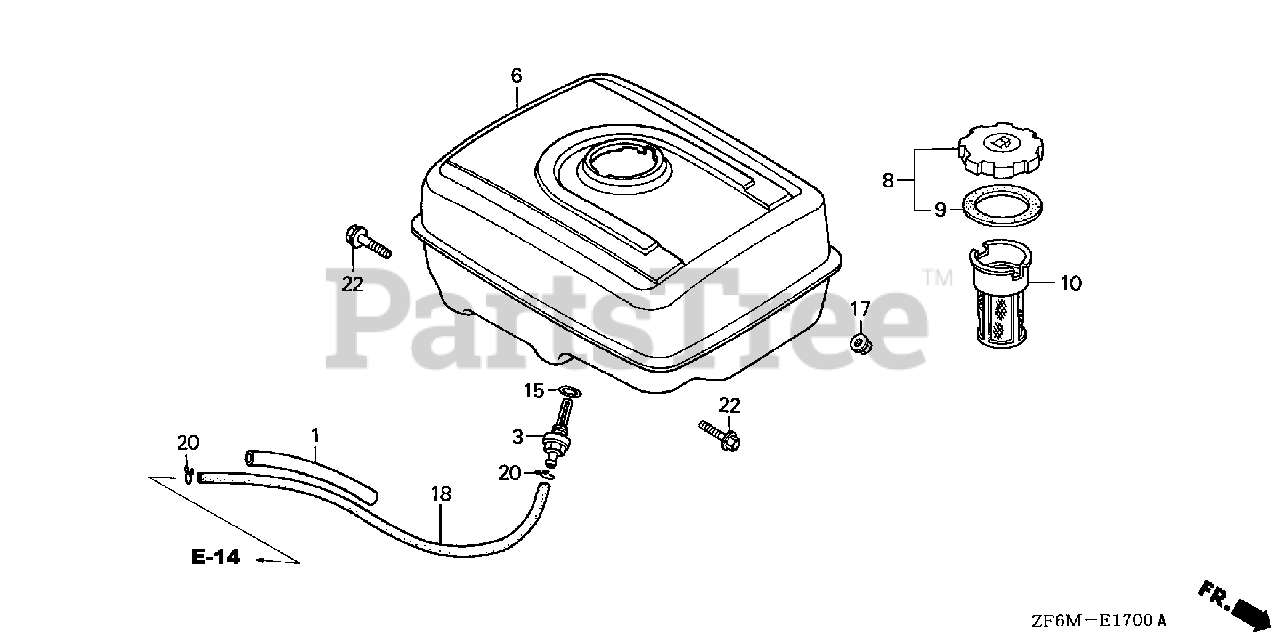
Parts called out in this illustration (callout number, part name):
1	RUBBER, SUPPORTER (107MM)
3	JOINT, FUEL TANK
6	TANK, FUEL *NH31* (MCKINLEY WHITE)
8	CAP, FUEL FILLER
9	GASKET, FUEL FILLER CAP
10	FILTER, FUEL
15	O-RING (13.5X1.5) (ARAI)
17	NUT, FLANGE (8MM)
18	BULK HOSE, FUEL (4.5X3000) (4.5X235)
20	CLIP, TUBE (B8)
22	BOLT, FLANGE (8X25)
